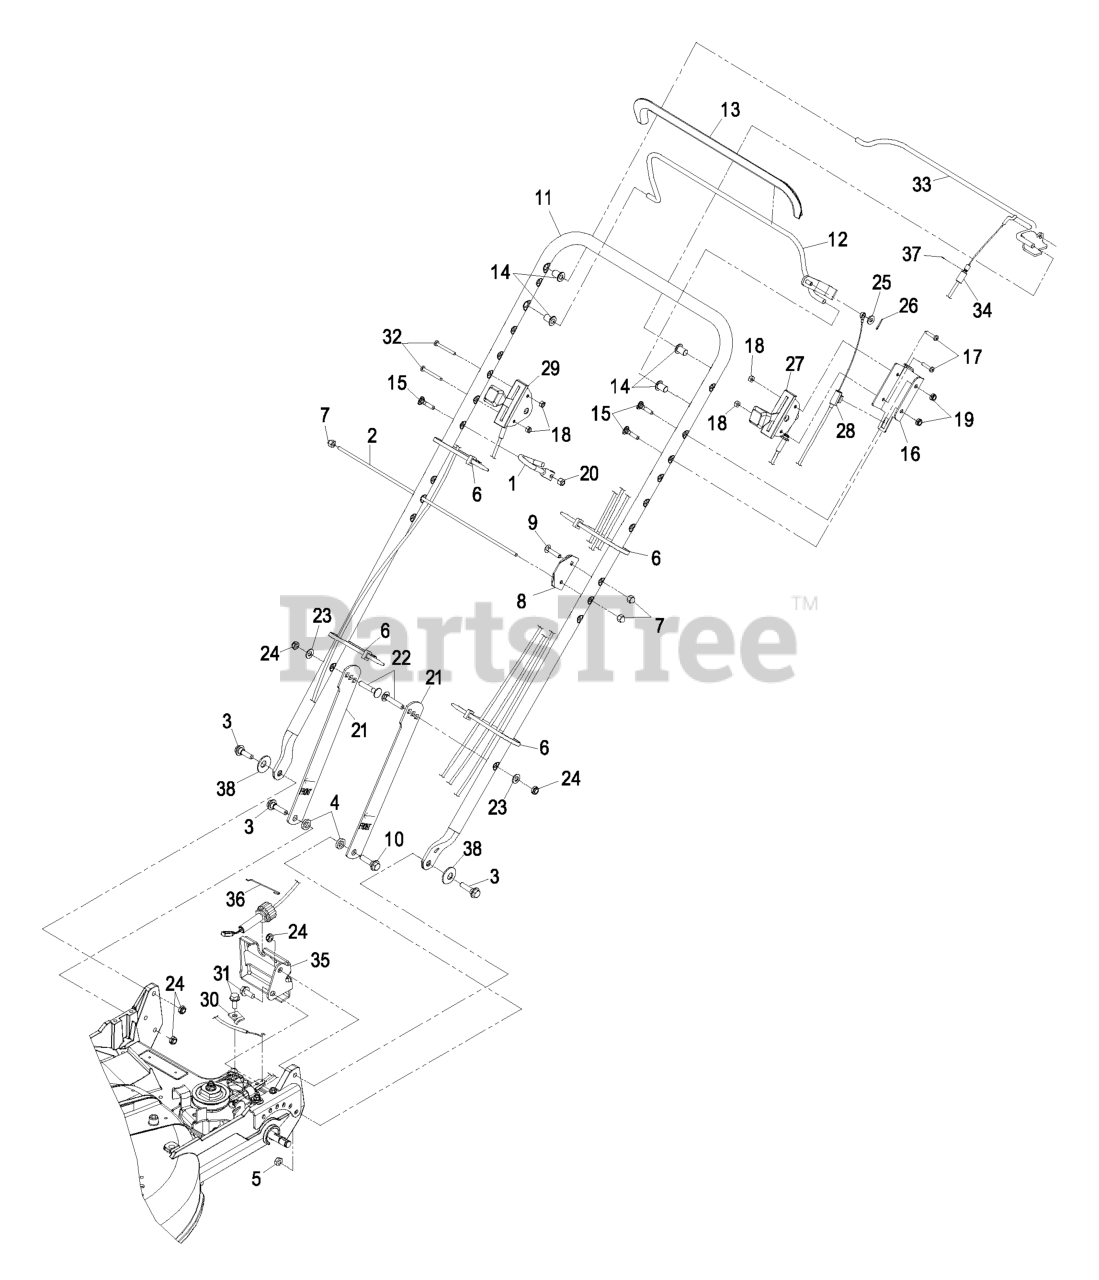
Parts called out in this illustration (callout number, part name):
1	GUIDE-ROPE
2	ROD,BAG SUPPORT
3	SCREW-SHOULDER
4	SPACER
5	NUT-LOCK, NI
6	TIE-CABLE
7	NUT-CAP
9	SCREW-CARR
10	SCREW-SHOULDER
12	WLD,BAIL DEADMAN (PLATED)
13	PAD,DEADMAN
14	BUSHING
15	SCREW-HANDLE
16	BRACKET,THROTTLE
17	SCREW-PPH
18	NUT-LOCK, NI
19	NUT-LOCK, NI
20	NUT-LOCK, NI
22	BOLT-CARR
23	WASHER-PLAIN
24	NUT-LOCK, NI
25	WASHER-FLAT
26	PIN-COTTER
27	CABLE,THROTTLE KAWASAKI
28	CABLE,BRAKE KAWASAKI
29	CABLE,SHIFTER
30	CLAMP-CABLE
31	Screw-HWH 5/16-18 X 3/4 Tf
32	SCREW-PPH
33	WLD,BAIL TRACTION (PLATED
34	CABLE,TRACTION
35	BRACKET-ADJUSTMENT, TRACT
36	RETAINER-CABLE
38	WASHER-SPRING
